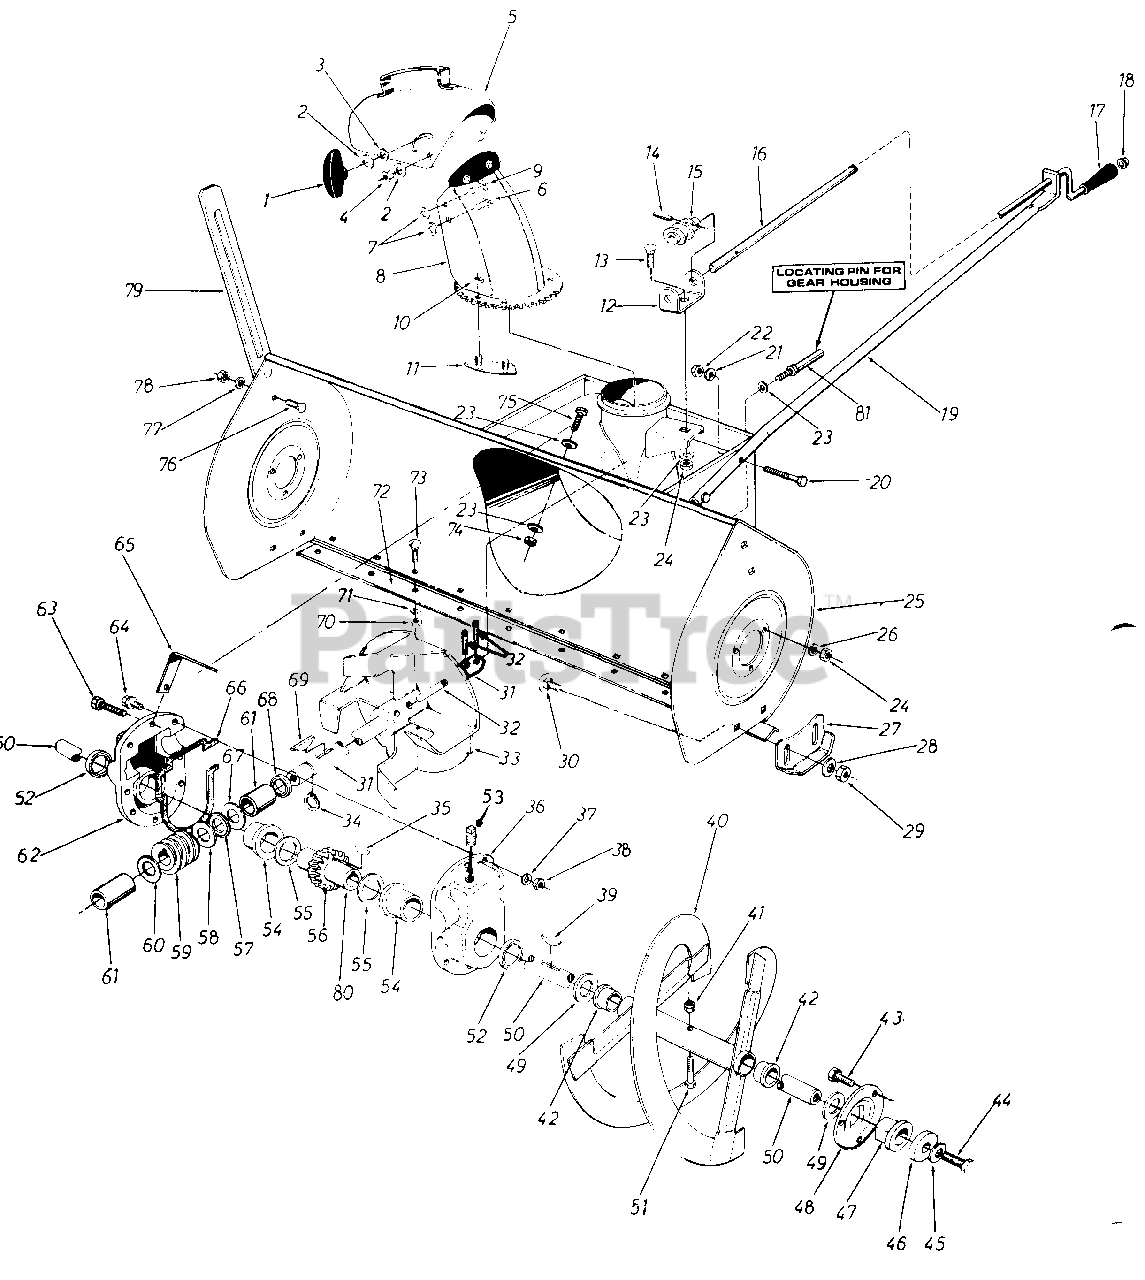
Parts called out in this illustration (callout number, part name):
1	Hand Knob Ass'y.
2	Bell. Wash. .345 I.D. x .88 O.D. x .060
3	Fl.-Wash. .312 I.D. x 1.125 O.D. x .125
4	Hex Cent. L-Nut 5/16-18 Thd.
5	Top Chute Ass'y.
6	Carriage Bolt 5/16-18 x 1.50" Lg.
7	Fl.-Wash. .53 I.D. x 1.25 O.D. x .100
8	Chute Ass'y.
9	Carriage Bolt 5/16-18 x 1.00" Lg.
10	Hex Cent. L-Nut 1/4-20 Thd.
11	Chute Flange Keeper Ass'y.
12	Chute Bracket
13	Carriage Bolt 5/16-18 x .62" Lg.
14	Spring Pin Roll 1/8" Dia. x .75" Lg.
15	Worm-R.H. w hree Threads
16	Chute Crank
17	Knob Black 3/8" Dia. Hole
18	Push Nut 3/8" rod.
19	Chute Crank Support Tubins
20	Hex Scr. 3/8-24 x 1.25" Lg. *
21	L.-Wash. 3/8" Scr.*
22	Hex Ins. Jam L.-Nut 3/8-24 Thd.
23	Bell.-Wash. .345 I.D. x .88 O.D. x .060
24	Hex Nut 5/16-18 Thd.
25	Blower Housing Assembly
26	L-Wash. 5/16" Scr.*
27	Slide Shoe
28	Bell. Wash. .400 I.D. x .88 O.D. x .060
29	Hex Nut 3/8-16 Thd.
30	Carriage Bolt 3/8-16 x .75" Lg.
31	Blower Axle
32	Spring Pin Spiral 5/16" Dia. x 1.75" Lg.
33	Blower Fan Ass'y.
34	Snap Ring for .875" Dia. Shaft
35	#91 Woodruff Key 1/4" x 3/4" Dia.
36	Gear Housing Half-L.H.
37	L.-Wash. 5/16" Scr.*
38	Hex Ins. L.-Nut 5/16-18 Thd.
39	#91 Woodruff Key 1/4" x 3/4" Dia.
41	Hex Ins. L-Nut5/16-18 Thd.
42	Plastic Bushing
43	Hex Sems Scr. 5/16-18 x .75" Lg.
44	Hex Scr. 5/16-18 x .88" Lg. Speco
45	Belleville Wash. .345" I.D. x .88" O.D.
46	Wash. .390 I.D. x 1.75" O.D. x 3/16" Thk.
47	Flange Bearing w/flats 1.00" I.D.
48	Bearing Housing
49	Fl-Wash. 1.00" I.D. x 1.75" O.D. x .100
50	Spiral Axle
51	Hex Scr. 5/16-18 x 1.75" Lg.*
52	Oil Seal-1.50" I.D.
53	Sq. Hd. Pipe Plug 3/8" Thd.
54	Flange Bearing 1.503 I.D.
55	Fl.-Wash. 1.50" I.D. x 2.0" O.D. x .030
56	Double Threaded Worm Gear-L. H.
57	Thrust Bearing.88" I.D. x 1.44" O.D.
58	Fl.-Wash. .88" I.D. x 1.5" O.D. x .030
59	Double Threaded Worm-L.H.
60	Fl.-Wash. .88 I.D. x 1.4" O.D. x .155
61	Sleeve
62	Gear Housing Half-R.H.
63	Hex Scr. 5/16-18 x 1.25" Lg. *
64	Hex Scr. 5/16-18 x 1.00" Lg. *
65	Gear Housing Support Brkt.
66	Rubber Gasket
67	Fl.-Wash. .88" I.D. x 1.4" O.D. x .155
68	Oil Seal. .875" I.D.
69	#9 Hi-Pro Key 3/16" x 3/4" Dia.
70	Hex Nut 5/16-18 Thd.
71	L.-Wash. 5/16" Scr.
73	Carriage Bolt 5/16-18 x .75" Lg.*
74	Hex Nut 5/16-18 Thd.*
75	Hex Scr. 5/16-18 x .75" Lg.*
76	Carriage Bolt 5/16-18 x .62" Lg.*
77	L.-Wash. 5/16" Scr.*
78	Hex Nut 5/16-18 Thd.*
79	Guide Blade
80	Worm Gear Shaft
81	Stud 3/8-16 x 2.75" Lg.
